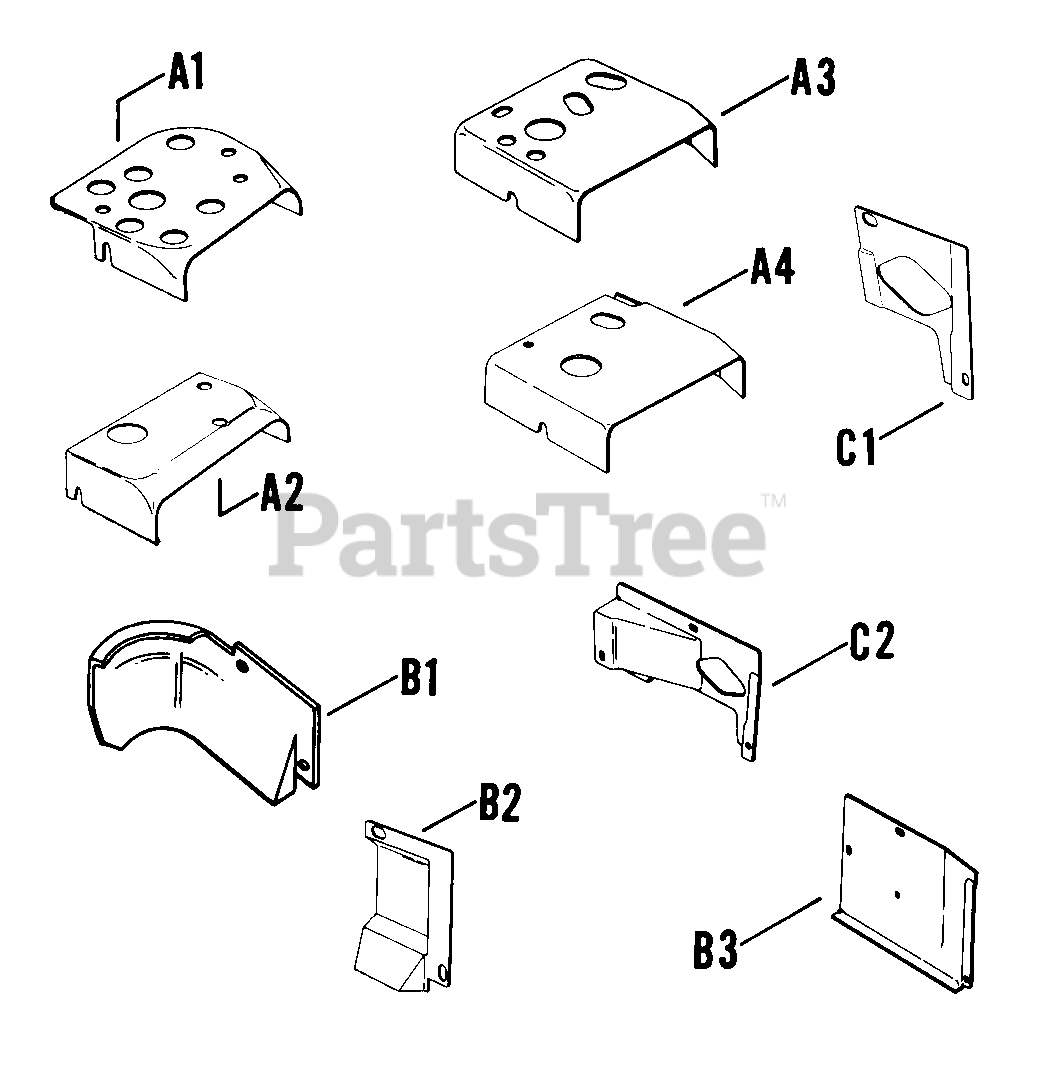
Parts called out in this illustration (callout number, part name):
A1	BAFFLE, HEAD
B1	BAFFLE, CYLINDER AIR
C1	BAFFLE, SIDE AIR
